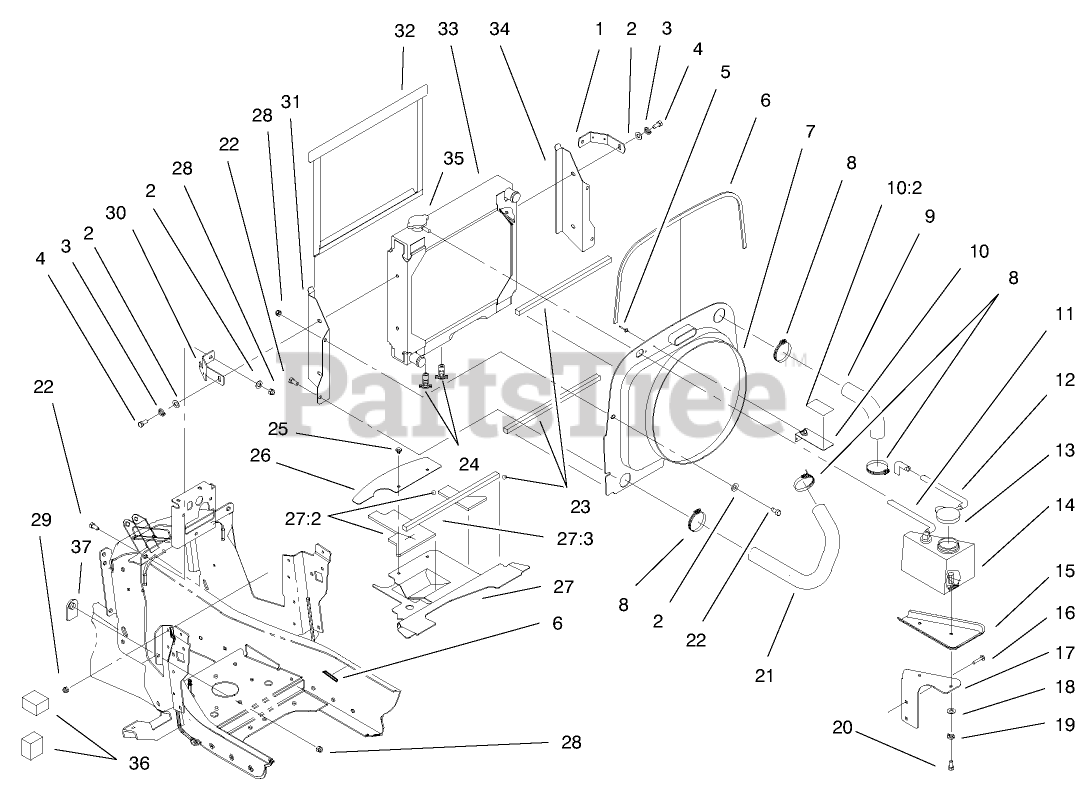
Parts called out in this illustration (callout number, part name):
2	WASHER-PLAIN
3	WASHER-LOCK
4	SCREW-HH
5	RIVET-POP
6	TRIM - LOC, 6"
6	TRIM - LOC 31"
7	SHROUD - FAN
8	CLAMP-HOSE
10	FAN/DECAL ASM
10:2	DECAL - WARNING
12	HOSE - OVERFLOW
14	BOTTLE - OVERFLOW
15	TRAY - OVERFLOW
16	BOLT-CARR
18	WASHER-FLAT
19	WASHER-LOCK
20	SCREW-HH
21	HOSE - RAD. DAIHATSU
22	SCREW-HH
23	FOAM - RADIATOR/SHROUD
25	RIVET - PLASTIC
26	BAFFLE - TOWER REAR
27	BAFFLE-TOWER ASM
27:2	FOAM - BAFFLE
27:3	FOAM - RADIATOR/SHROUD
28	NUT-LOCK, NI
29	NUT-HEX
33	RADIATOR - DIESEL
35	CAP-RADIATOR
36	SEAL-FOAM, SIDE
37	WASHER - SPACER
